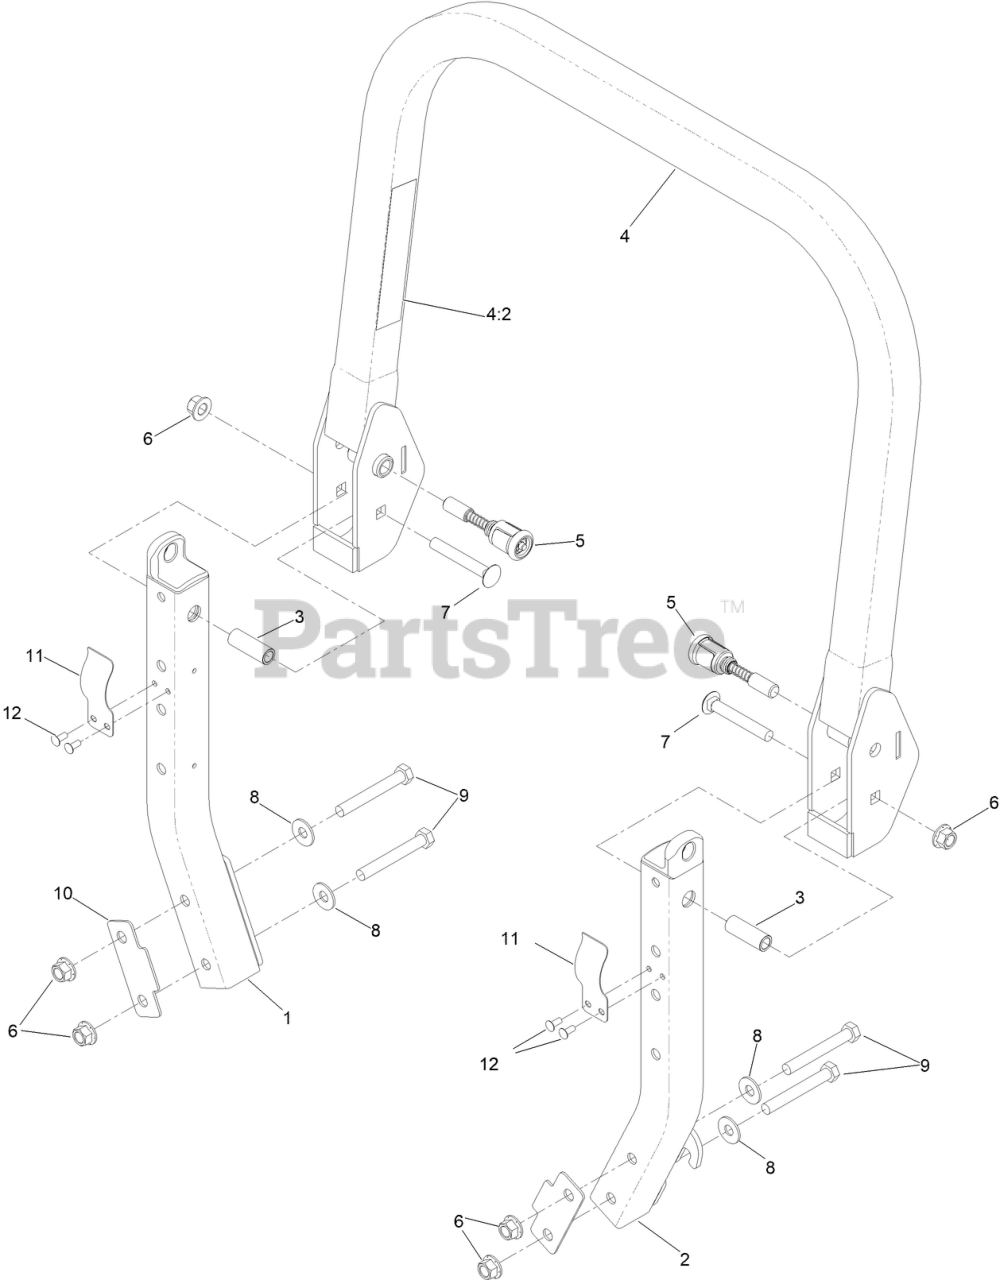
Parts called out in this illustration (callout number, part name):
1	Lower-ROPS, RH
2	Lower-ROPS, LH
4	ASM,ROPS UPPER W/DECAL
4:2	DECAL-WARNING
5	PIN-SPRING
6	Nut-Lock 1/2-13
7	SCREW-CARR
8	WASHER-SPRING
9	SCREW-HH
11	SPRING-LEAF
12	RIVET-BLIND
